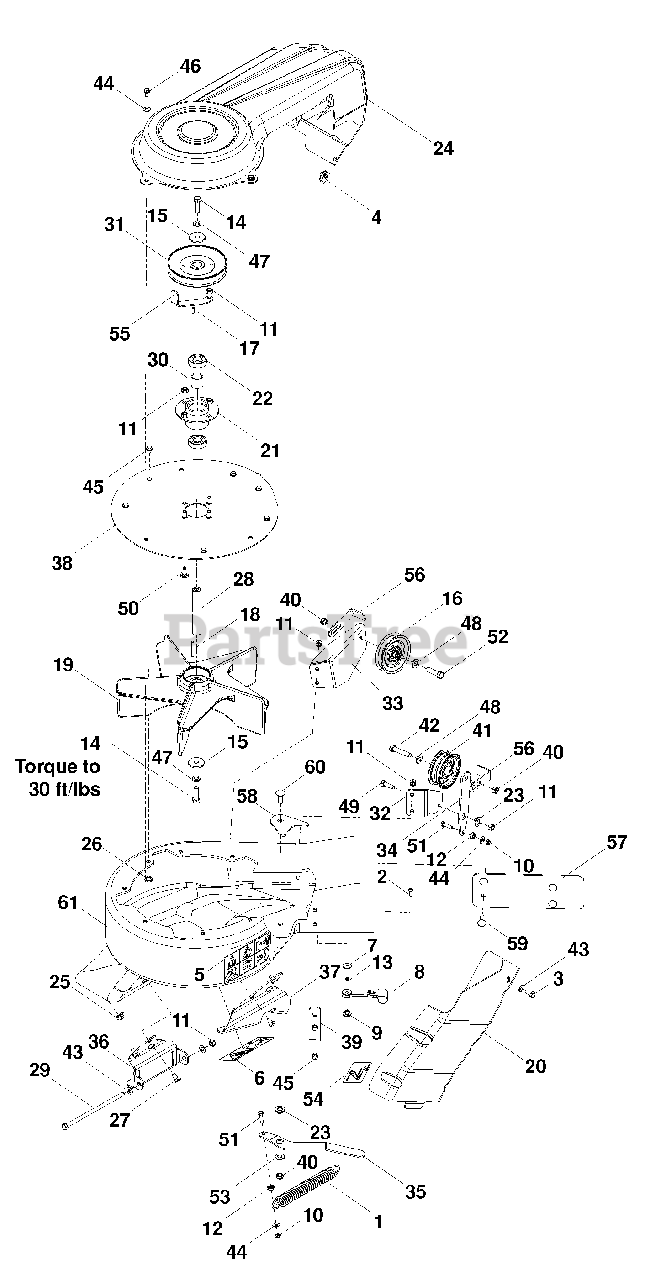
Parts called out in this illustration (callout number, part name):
1	Traction Spring
2	Screw 10-24 X 5/8 Rd Hd
3	Hcs 5/16-18 X 3/4
4	Retainer U Type
5	Decal, Warning
6	Decal, Severing
7	Washer 3/16 X 3/4 X 16 Ga
8	Latch, Hood
9	Weld Nut, Plated
10	Nut 1/4 -20 Hex Nyloc
11	Nut 5/16-18 Hex Nyloc
12	Nut /4 -20 Hex Flange
13	Washer 3/16 Lock
14	Bolt, Hex 3/8-24 X 11/4 Gr 8
15	Washer, Hardened
17	Key 3/16 X 1/2
18	Key 3/16 X 11/2
20	Cover, Belt
21	Hub, Bearing
24	Cover, Outer Pulley
25	Nut 5/16-18 Tee
26	Nut 1/4-20 Tee
27	Hcs 5/16-18 X 1/2
28	Shaft, Impeller
29	Hcs 5/16-18 X 7
32	Mount, Idler, Upper
33	Mount, Idler, Lower
34	Arm, Idler
35	Arm, Tension
36	Brac Ket, Moun T, Front
37	Brac Ket, Moun T, Rear
38	Plate, Outer
40	Nut 3/8-16 Hex Jam Nyloc
41	Pulley, Idler
42	Hcs 3/8-16 X 13/4
43	Washer 5/16 Sae Flat
44	Washer 1/4 Flat Sae
45	Screw 1/4 X 3/8 Thrd Frm
46	Hcs 1/4 -20 X 1/2
47	Washer 3/8 Splt Lock
48	Washer 3/8 Sae Flt
49	Hcs 5/16-18 X 1
50	Rhsnb 5/16-18 X 3/4
51	Hcs 1/4-20 X 7/8
52	Hcs 3/8-16 X 11/2
53	Washer 5/16 Std Flt
54	Decal, Belt Routing
55	Keeper, Belt, Outer
56	Keeper, Belt, Rear
57	Plate, Backing
58	Plate, Backing
59	Rhsnb 5/16-18 X 1
60	Rhsnb 3/8-16 X 1
61	Housing W/Decals
